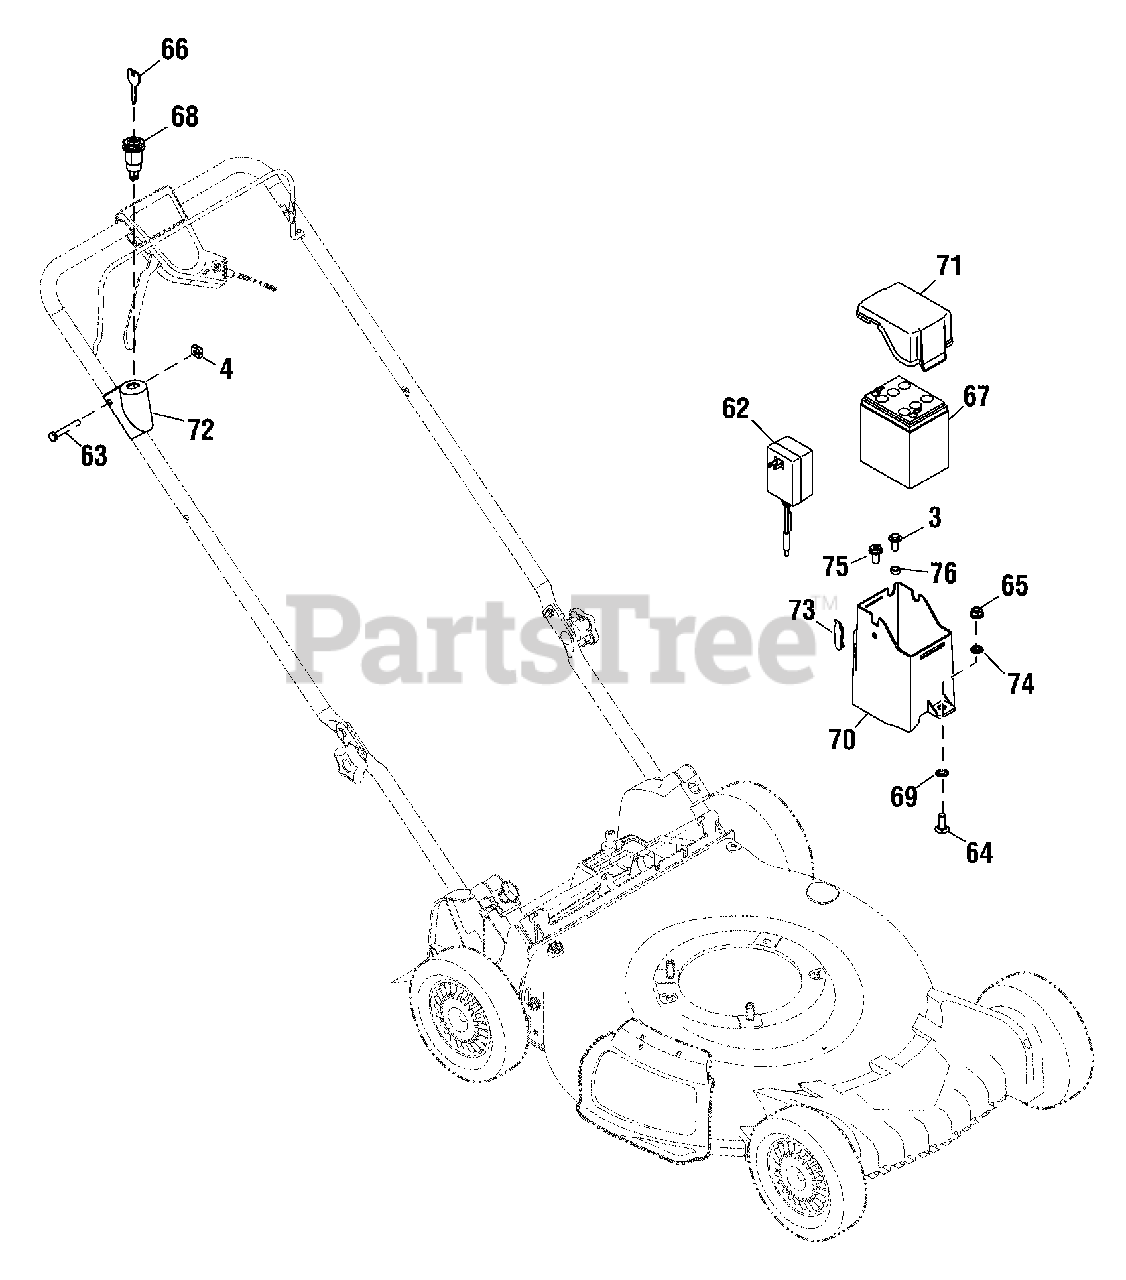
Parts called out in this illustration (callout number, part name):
3	SCREW, 5/16-14 x 3/4
4	NUT, Square, 1/4-20
62	CHARGER, Battery
63	SCREW, 1/4-20 x 1.75
64	BOLT, Carriage, 5/16-18 x 1
65	NUT, Serrated Lock Flange, 5/16-18
67	BATTERY
69	NUT, Speed
70	HOUSING, Battery
71	HOUSING, Top, Battery
72	HOUSING, Electric Start
73	SEAL, Lid
74	WASHER, Bell, .340 x .872 x .080
75	BOLT, Shoulder, 5/16-14 x .972
76	SPACER, .340 x .460 x .246
